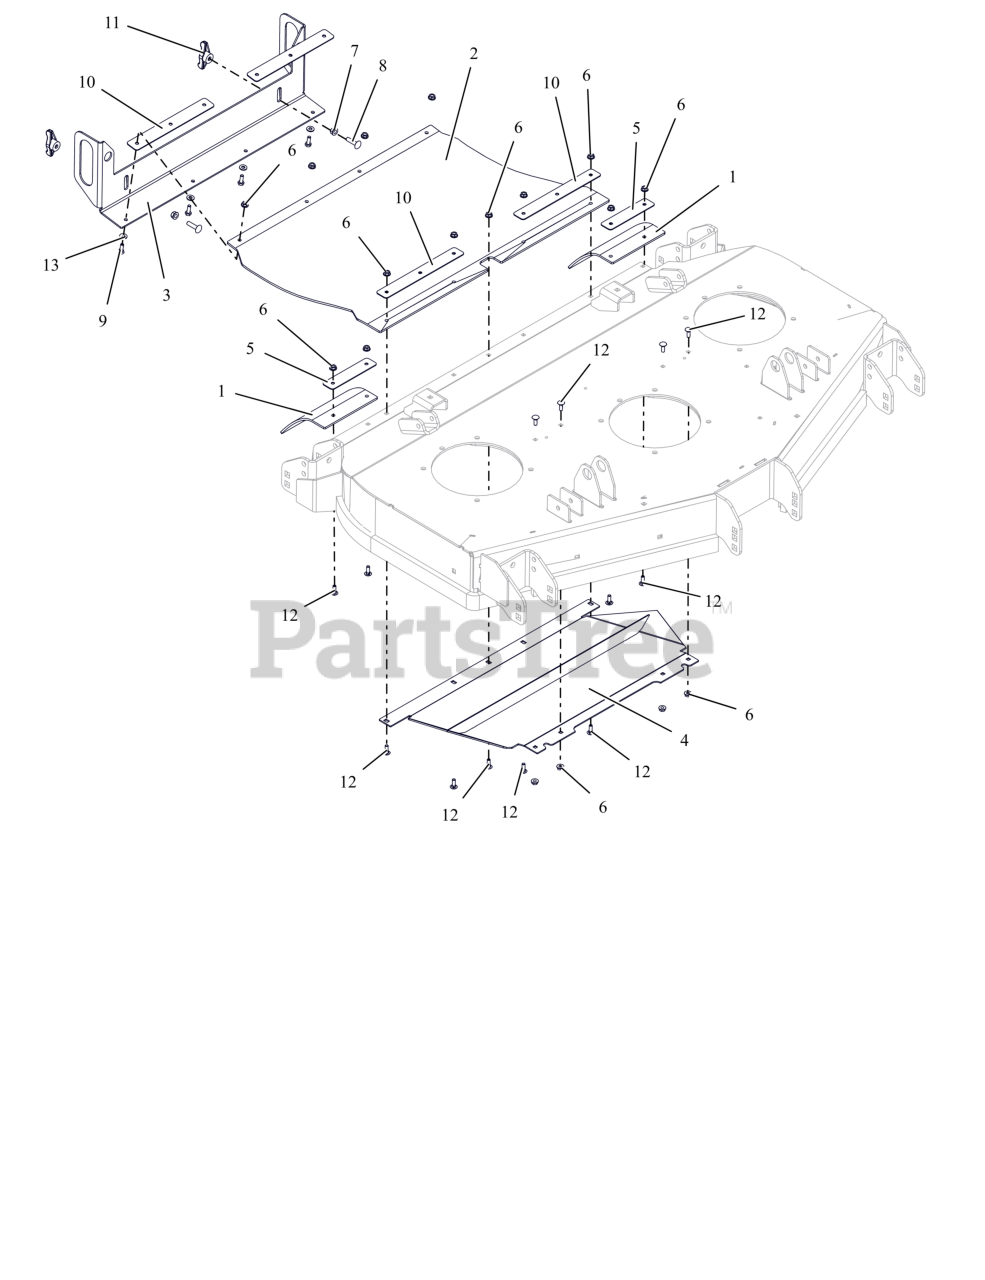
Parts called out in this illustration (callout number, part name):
1	FLAP, REAR DISCHARGE 48" TIRE
2	CHUTE, REAR DISCHARGE
3	HANDLE, CHUTE MOUNTING (ORANGE)
4	WLDMT, DEFLECTOR BAFFLE (ORANGE)
5	PLATE, 52" TIRE CHUTE MTG (BLACK)
6	NUT-LK-CTR-FLG .25-20 ZC120
7	NUT,LK-CTR-FLG .31-18 GF ZCC
8	BLT, RHSSN.31-18X1.25 G5 ZCC
9	BLT, HEX .25-20X.75 G5 ZCC
10	PLATE, CHUTE MTG (BLACK)
11	KNOB,WING .31-18 UNC NYL/TALC
12	BLT, RHSN .25-20X.750 G5 ZCC
13	WSHR,FLT .281X.625X.065 ZCC
